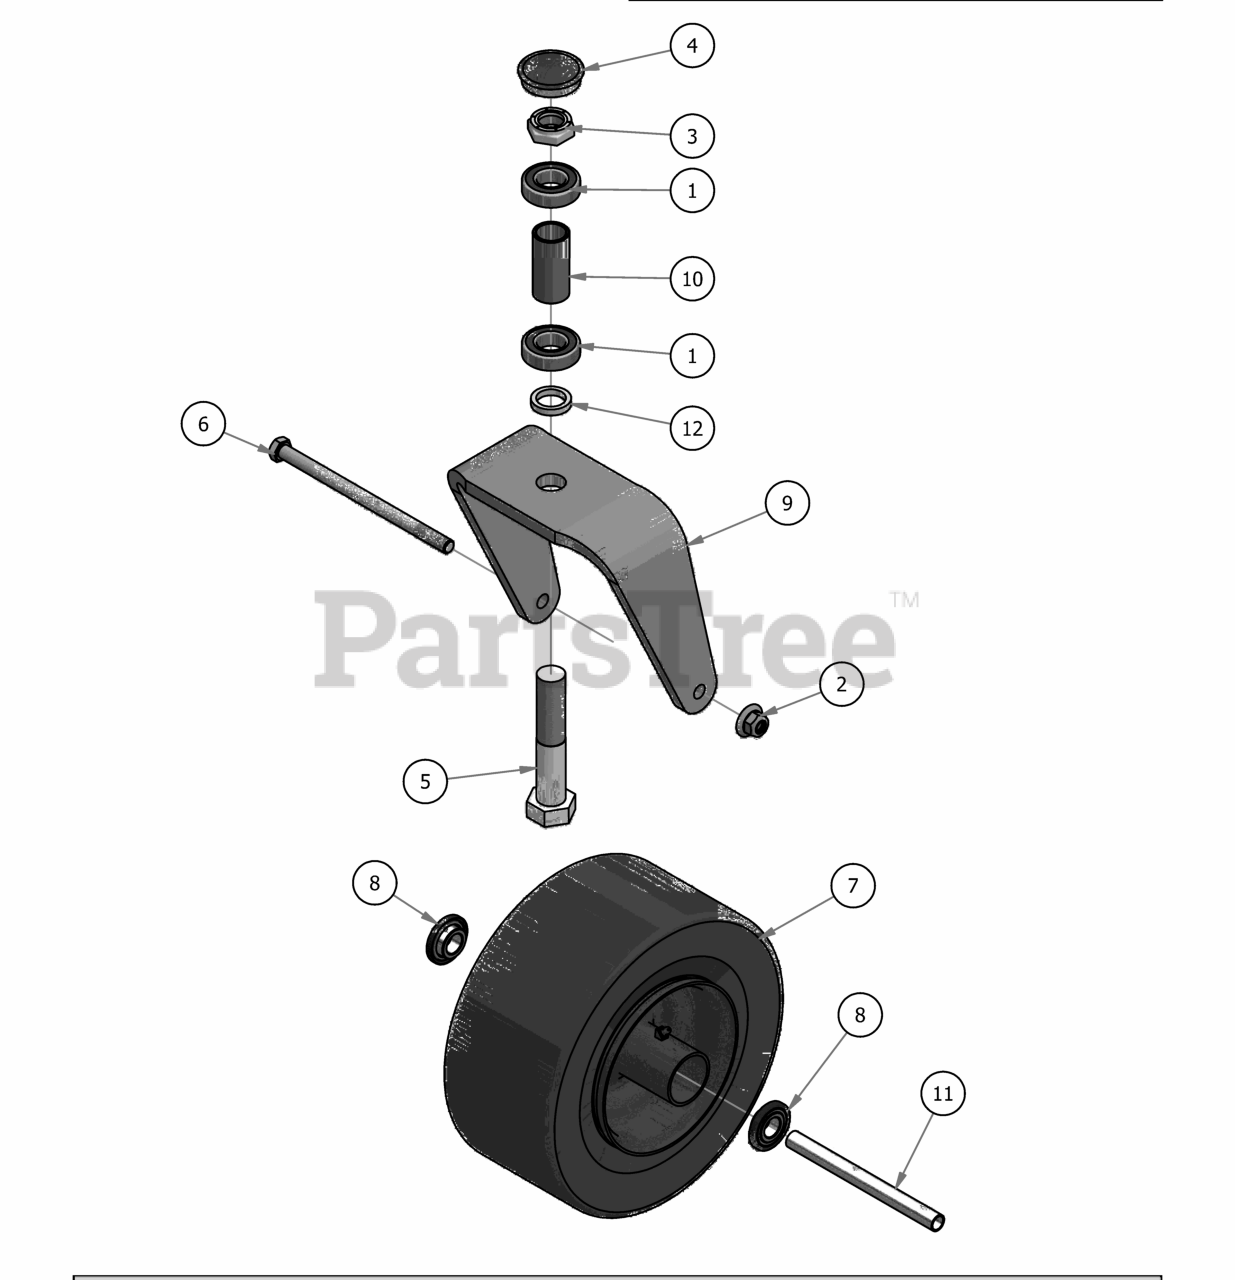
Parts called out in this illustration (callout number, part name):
1	Caster Bearing 2016 - 1641 Bearing
2	1/2-13 Nylon Insert Flange Nut
3	1" Fine Thread 1/2 Nylock Nut
4	2017 Bearing Cover
5	1-14 x 5 Hex Bolt Grade 8 Zinc Yellow
6	1/2" x 8 1/2 GR 5 Hex Bolt
7	Tire & Wheel Assembly
9	2017 ZT Front Fork
10	2016 Front Bearing Spacer
11	Front Wheel Spanner
12	MZ Bar Stop
